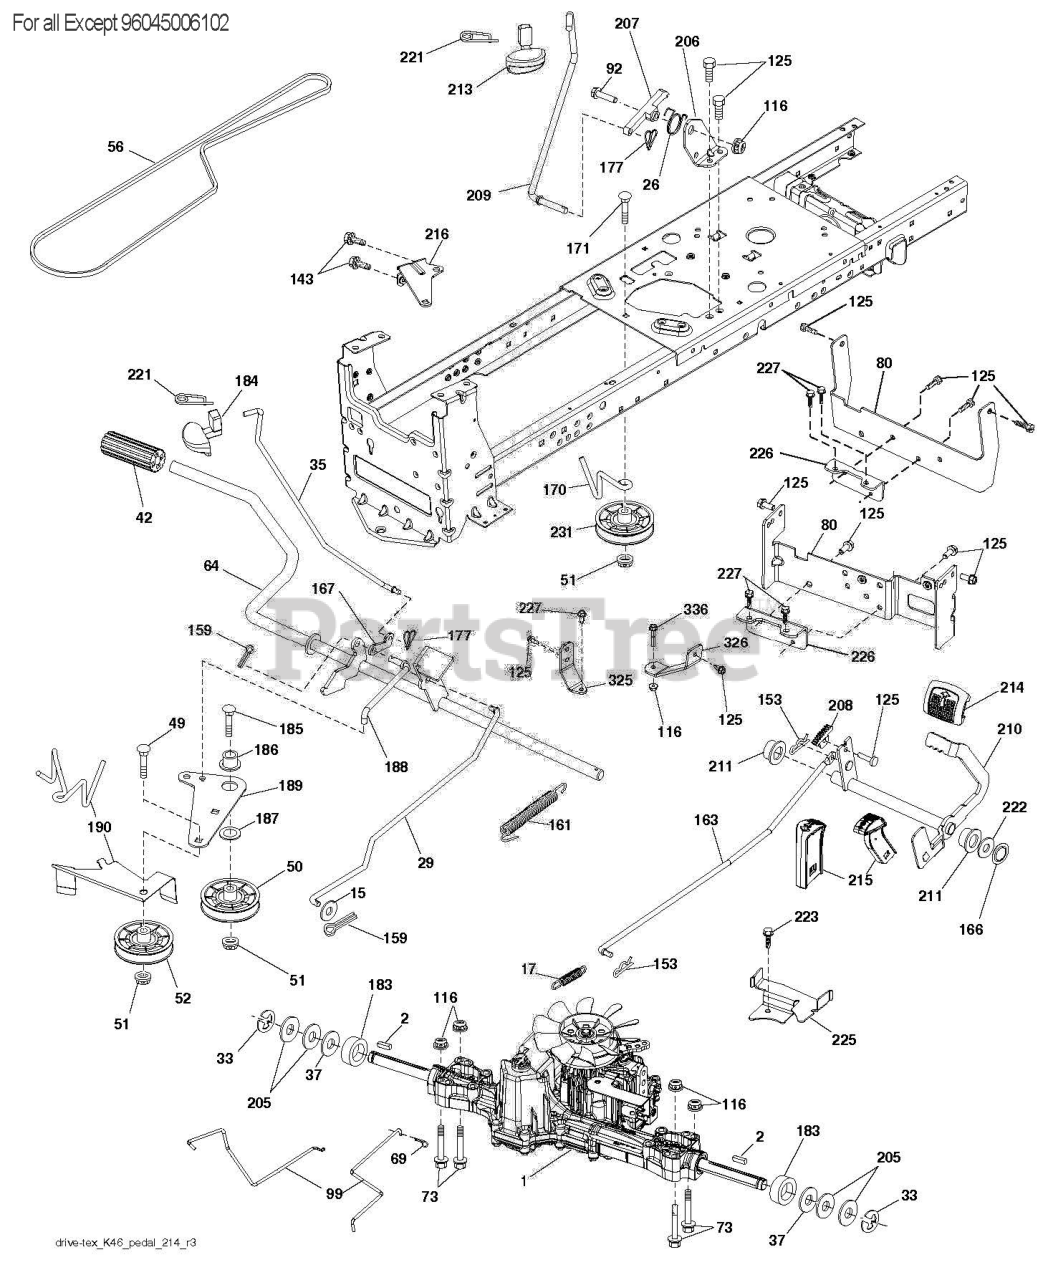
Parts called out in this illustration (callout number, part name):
2	SQUARE KEY
15	WASHER
15	WASHER PLAIN WASHER 3/8 X 0.08
17	SPRING.BRAKE.K46.GREEN
26	SPRING.RETURN.CRUISE
29	ROD.BRAKE.K46
35	ROD ROD.PARKINGBRAKE.GT.HUSQ/P
35	ROD .BRAKE. PARKING. GT. HUSQ.
37	WASHER.HARDENED
42	PEDAL COVER
49	BOLT
49	Bolts
50	IDLER.FLAT.910.OFFSET
51	NUT LOCK FLG 3/8-16 UNC
52	IDLER.V-GROOVE.910.OFFSET
56	Belts
56	V-BELT.MOWER.92.40.42/K46
64	SHAFT.ASM.PEDAL.BRK.CNTR
69	HAIRPIN.SOFT.ZINC.059X1.125
73	Bolts
73	BOLT
73	BOLT HEX 5/16-18 GR 5
80	STRAP.TORQUE.K46.K57R.TT
99	ROD.SPRING.BYPASS.K46.LT.Z
99	ARM.PIVOTING.TCRD.GEN2.5.BAGGE
125	SCREW
153	RETAINER M
159	Pins
159	COTTER PIN
161	SPRING, RETURN LT
163	ROD.CONTROL.K57R.K46
163	Rods
166	NUT.PUSH.625
167	LATCH.BRAKE.SPRING
170	KEEPER.V-IDLER.CENTER.
170	KEEPER.CENTER SPAN.1.688
171	BOLT
171	Bolts
177	RETAINER CLIP
177	PIN COTTER;LOCKING;BOWTIE;1IN
183	SPACER AXLE
184	HANDLE.PARKING.BRAKE.H (BLK)
186	SPACER.RETAINER
188	LINK.CLUTCH.GROUND DRIVE.LONG
189	BELLCRANK.GROUND.DRIVE.TEX.
190	KEEPER.BELLCRANK.DRIVE
206	BRACKET.MOUNT.CRUISE.LATCH
207	Latch
207	LATCH.CONTROL.CRUISE.TEX
208	GEAR.SECTOR.CONTROL.CR
208	Gears
209	ROD ROD.CRUISECONTROL.GT.HUSQ/
209	ROD.CONTROL.CRUISE.GT.
210	ROCKER.ASM.PEDAL.CONTR
211	BEARING.NYLON
213	KNOB.CONTROL.CRUSIE.HU
214	PEDAL.FORWARD.PAD.TEX
215	PEDAL.REVERSE.TEX.GT.4
215	PEDAL.COVER.REVERSE.CRD.X428BK
216	BRACKET.PULLEY.IDLER.W/TEX
221	RETAINER.SPRING.CLIP.H
222	WASHER 21/32 X 1-1/4 X 10 GA.
223	SCREW
223	BOLTS
225	KEEPER.BELT.TRANSAXLE.K46
226	BRACKET.MOUNT.TORQUE.K46.TLT
227	Bolts
227	SCREW.THDROL.5/16-18X3/4.TTY
231	IDLER.V-GROOVE.910.OFFSET
231	IDLER.V-GROOVE.1.688.OFFSET
325	BRACKET.TRQ.STP.46.20".TIRE.LH
326	BRCKT.PNT.TRQ.STP.46.20TIRE.RH
336	Bolts
336	BOLT.5/16-18X1-3/4.FLANGED.HEX
